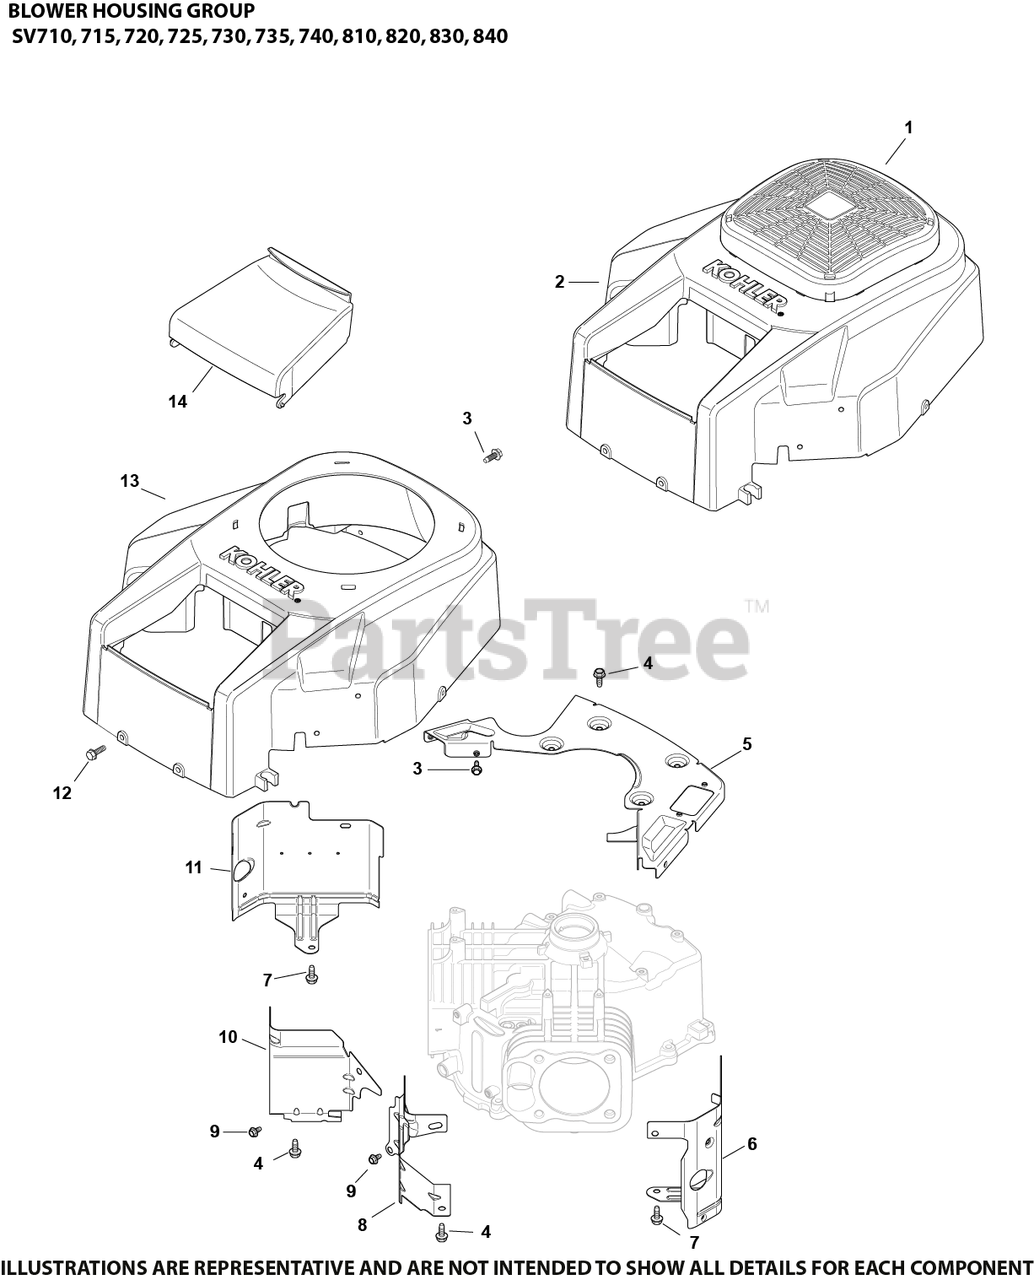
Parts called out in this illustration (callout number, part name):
1	GUARD, FIXED
2	KIT, BLWER HOUSING-FIXED GUARD - DISCONTINUED
3	SCREW, THREAD FORMING
4	SCREW, THREAD FORMING
5	KIT, BACKING PLATE - DISCONTINUED
6	BAFFLE, CYL BARREL - #2 SIDE
7	SCREW, THREAD FORMING
8	BAFFLE, VALLEY #2 CYLINDER
9	SCREW, THREAD FORMING
10	BAFFLE, VALLEY #1 CYLINDER
11	BAFFLE, CYL BARREL - #1 SIDE
12	SCREW, TAP M6X1.7X18
14	COVER, AIR CLEANER
